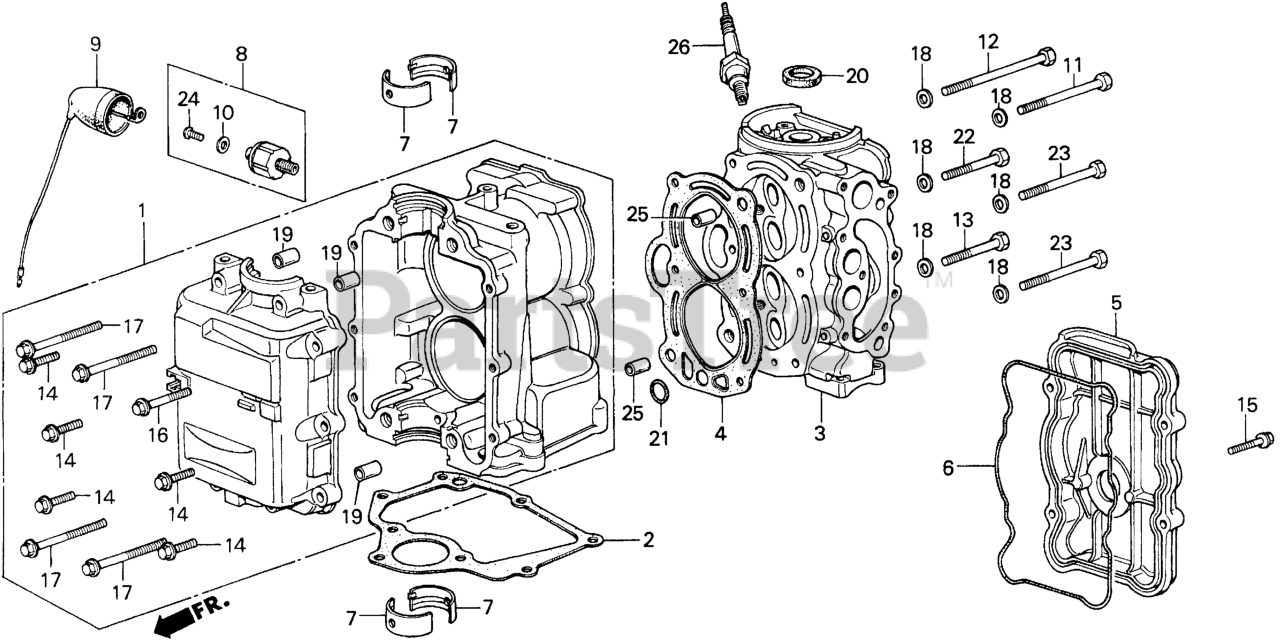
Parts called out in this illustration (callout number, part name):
1	CYLINDER ASSY.
2	GASKET, OIL PAN
3	CYLINDER HEAD (NOT AVAILABLE)
4	GASKET, CYLINDER HEAD
5	COVER, CYLINDER HEAD *NH8* (DARK GRAY)
6	GASKET, CYLINDER COVER
7	BEARING, CRANKSHAFT
8	SWITCH, OIL PRESSURE
9	WIRE, OIL PRESSURE SWITCH
10	WASHER (4MM)
11	BOLT, HEAD (8X70)
12	BOLT, HEAD (8X94)
13	BOLT, HEX. (8X55)
14	BOLT, FLANGE (6X25)
15	BOLT, FLANGE (6X28)
16	BOLT, FLANGE (6X35)
17	BOLT, FLANGE (8X45)
18	WASHER, HEAD (8MM)
19	PIN, DOWEL (10X12)
20	OIL SEAL (16X28X6)
21	O-RING (10.8X2.4) (ARAI)
22	BOLT, HEX. (8X50) (NOT AVAILABLE)
23	BOLT, HEX. (8X65) (NOT AVAILABLE)
24	SCREW, PAN (4X6)
25	PIN A, DOWEL (10X16)
26	SPARK PLUG (DR-4HS) (NGK)
26	SPARK PLUG (DR5HS) (NGK)
26	SPARK PLUG (X16FSR-U) (DENSO)
